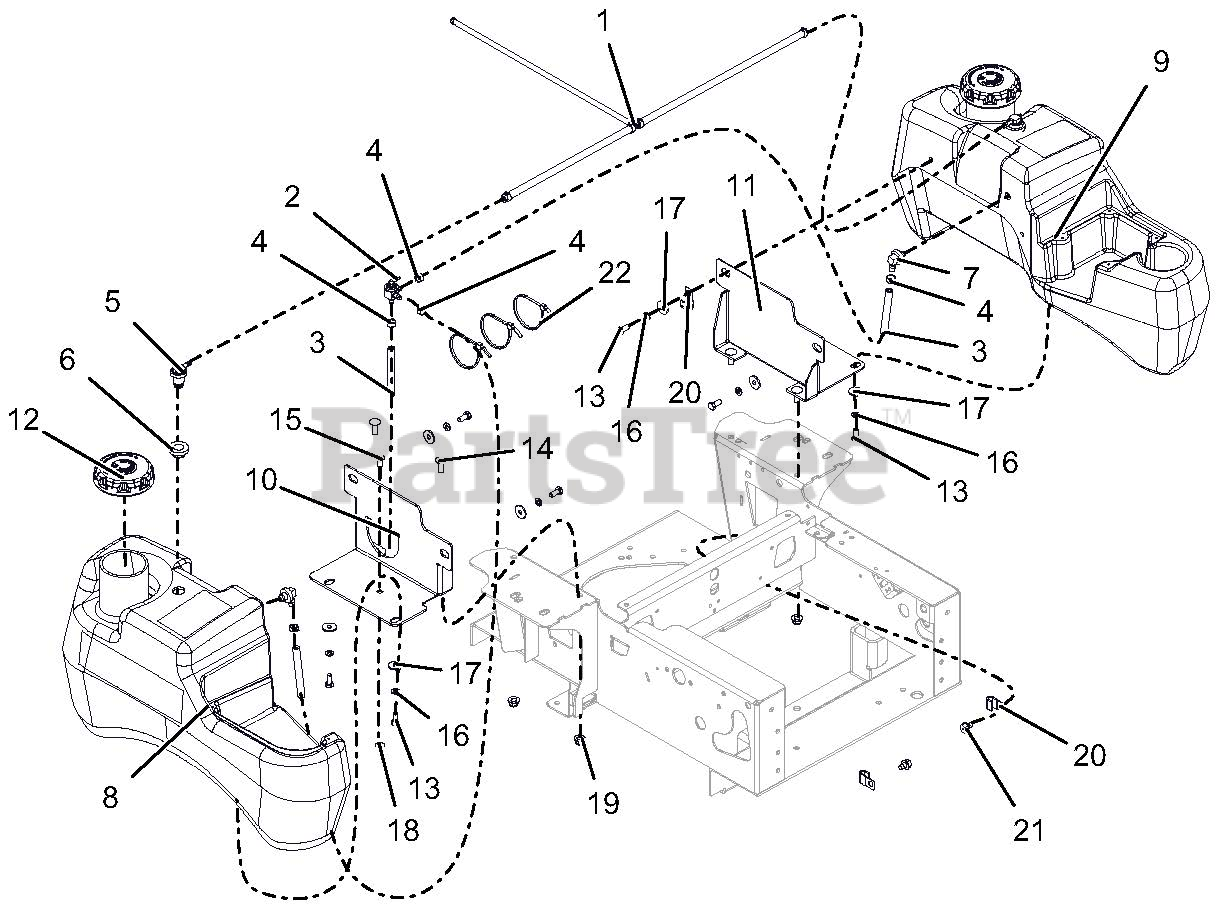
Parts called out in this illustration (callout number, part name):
1	ASM, FUEL PICK-UP - SML/ MED TANK
2	VALVE, FUEL
3	.25 LOW-PERM GAS HOSE
4	CLAMP, FUEL LINE
5	VALVE, 2-WAY
6	GROMMET, REMOTE VENT NITRILE
7	ASS’Y, SMALL/ MED TANK FUEL PICK-UP
8	TANK, GAS - RH MEDIUM GRAVELY
9	TANK, GAS - LH MEDIUM GRAVELY
10	BRKT, RH MEDIUM FUEL TANK MTG -RED
11	BRKT, RH MEDIUM FUEL TANK MTG - RED
12	CAP, FUEL VENT-IN AUTOLOCK
13	BLT-HEX .31-18X.75 GR5 YWZC
14	BLT-RDHDSHSQNK.38-16X1.0 G5YZ
15	BLT-RDHDSQNK .31-18X.75 G5 YWZC
16	WSHR-LK .31X.078 REG YWZC
17	WSHR-FL-STL .328X1.00X.094 YWZC
18	NUT-LK-NYL-FLG .31-18 YWZC
19	NUT-LK-NYL-FLG .38-16 YWZC
20	CLAMP, J
21	SCR-TAP .38-16X.50 HWH TR YWZ
22	CABLE, TIE 5.50 LG
